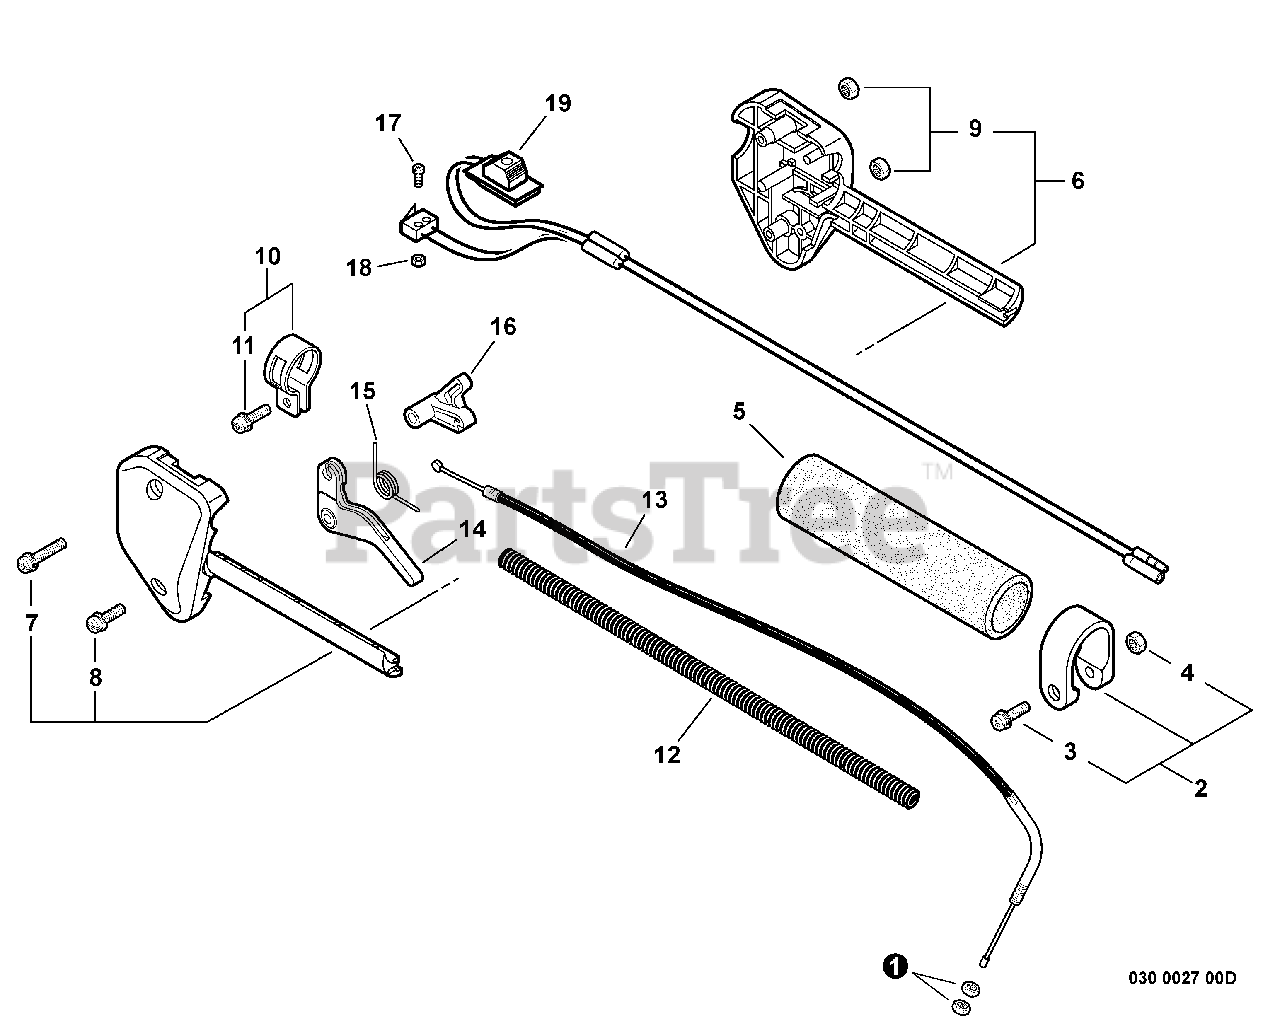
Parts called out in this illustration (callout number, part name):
2	CLAMP KIT
3	SCREW 5×28
4	NUT M5
5	GRIP, HANDLE
6	CONTROL HANDLE KIT
7	SCREW 5×35
8	SCREW 5×25
9	NUT M5
10	CLAMP KIT
11	SCREW 5×14
12	TUBE, FLEXIBLE
13	CABLE, THROTTLE
14	TRIGGER, THROTTLE
15	SPRING, TORSION
16	LOCKOUT, THROTTLE
17	SCREW 2×10
19	SWITCH, ON-OFF
